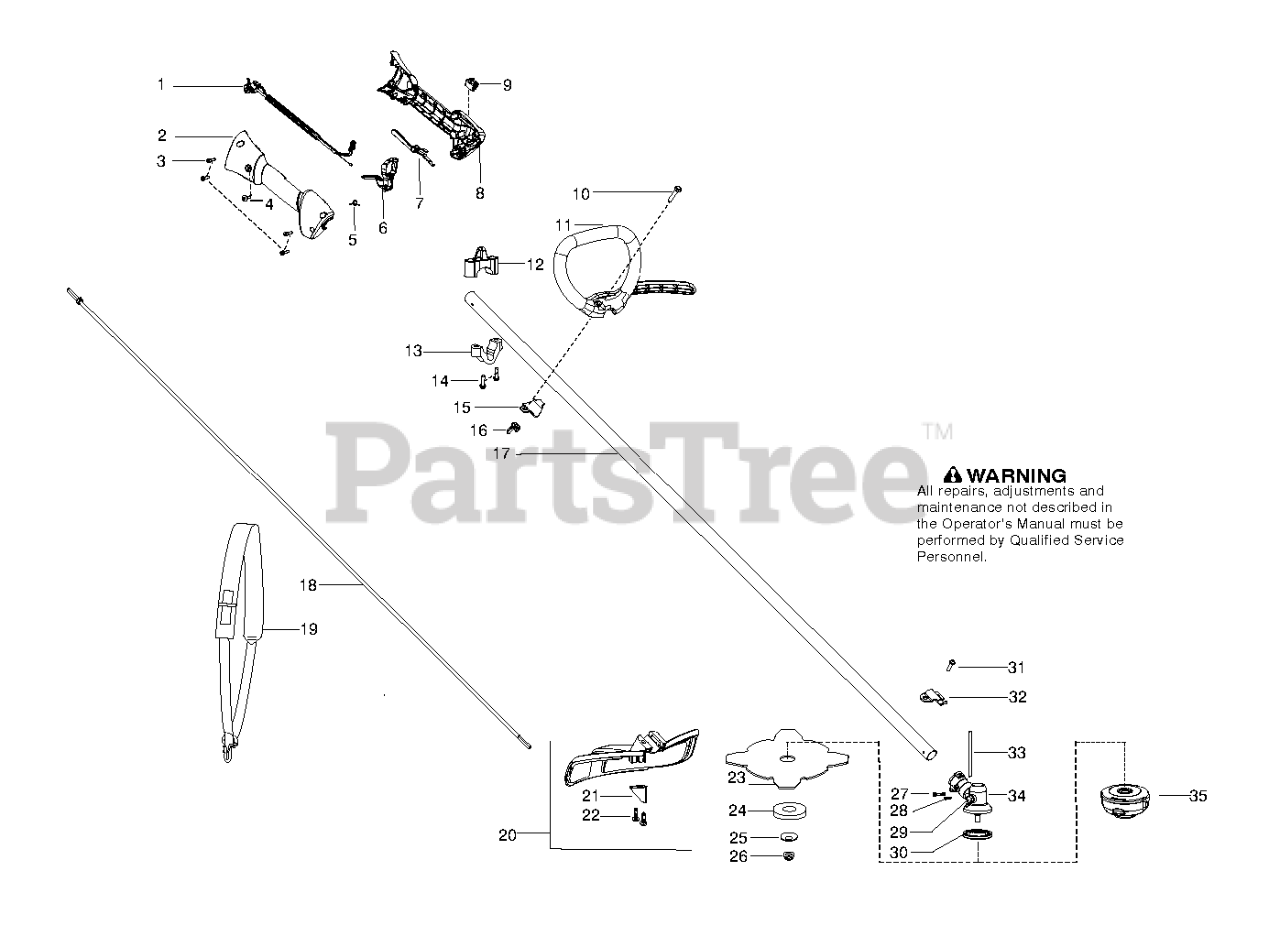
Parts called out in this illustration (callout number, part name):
1	ASSY CABLE / WIRE HARNESS
2	HSG THROTTLE RIGHT HVA
3	SCREW M4 X 1.75 PT 16MM
4	SCREW-10-14 X 1/2 PLASTITE
5	SPRING TRIGGER
6	TRIGGER THROTTLE HVA ORANGE
7	THROTTLE LOCKOUT HVA ORANGE
8	HSG THROTTLE LEFT HVA
9	SWITCH
10	BOLT, TYPE 2
11	ASSY HANDLE JBAR
12	CLAMP HARNESS UPPER
13	CLAMP HARNESS LOWER
15	CLAMP ASSIST HANDLE
16	WINGNUT, TYPE 2
17	KIT - DRIVESHAFT
18	FLEXSHAFT 57"
19	Harness-w/o warning
20	KIT COBI SHIELD
21	Limiter - Line
23	Blade - Grass
24	SUPPORTING CUP
25	SUPPORT FLANGE
26	GEARHEAD NUT - BRUSHCUTTER
27	SCREW - CARB. ADAPTOR
29	PLUG GREASE 9MM
30	DRIVE DISC
31	SCREW 1/4-20 X 7/8 (TAP
32	BRACKET SHIELD STRAIGHT SHAFT
33	LOCKING PIN
34	ASSY GEARBOX
35	T25 TRIM HEAD 10MM LH
